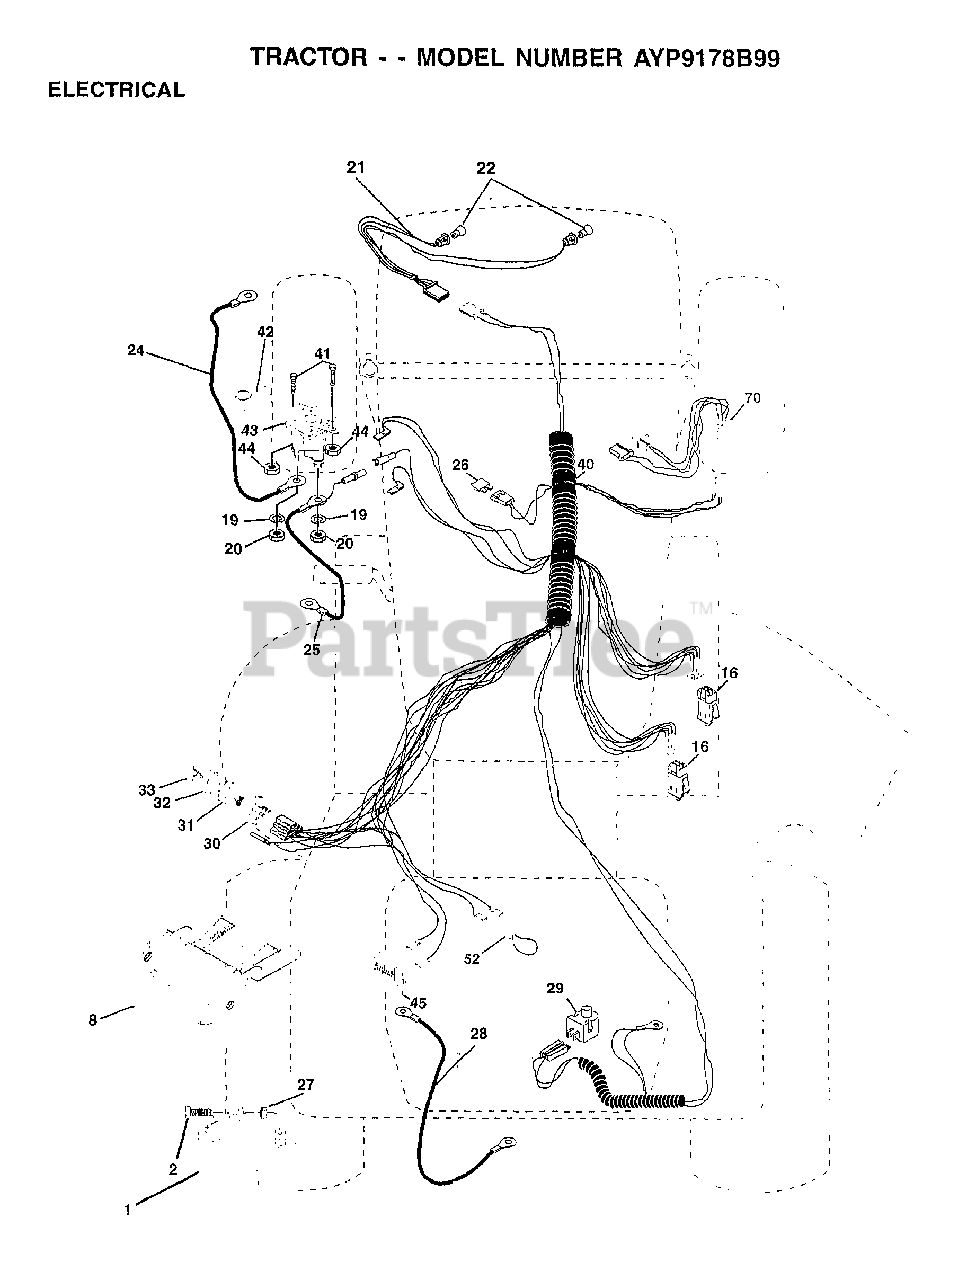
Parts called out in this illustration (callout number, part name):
2	BOLT LT
8	"CASE,BATTERY.MECH"
16	SWITCH INTERLOCK
20	NUT
21	HARNESS.ASM.LIGHT W/4152J
22	HEADLAMP BULB
24	"CABLE T, BATTERY"
25	CABLE.BTRY.6GA.RD
26	FUSE.15 AMP
27	NUT
28	CABLE T
29	SWITCH SEAT
30	SWITCH IGN 4POS
31	NUT IGNITION
32	COVER KEY SWITCH
33	KEY
40	HARNESS.IGNITION
41	BOLT HXHD FIN
44	NUT HXKEP 1/4X20
52	PROTECTION LOOP
70	HARNESS.ENGINE.B&S
